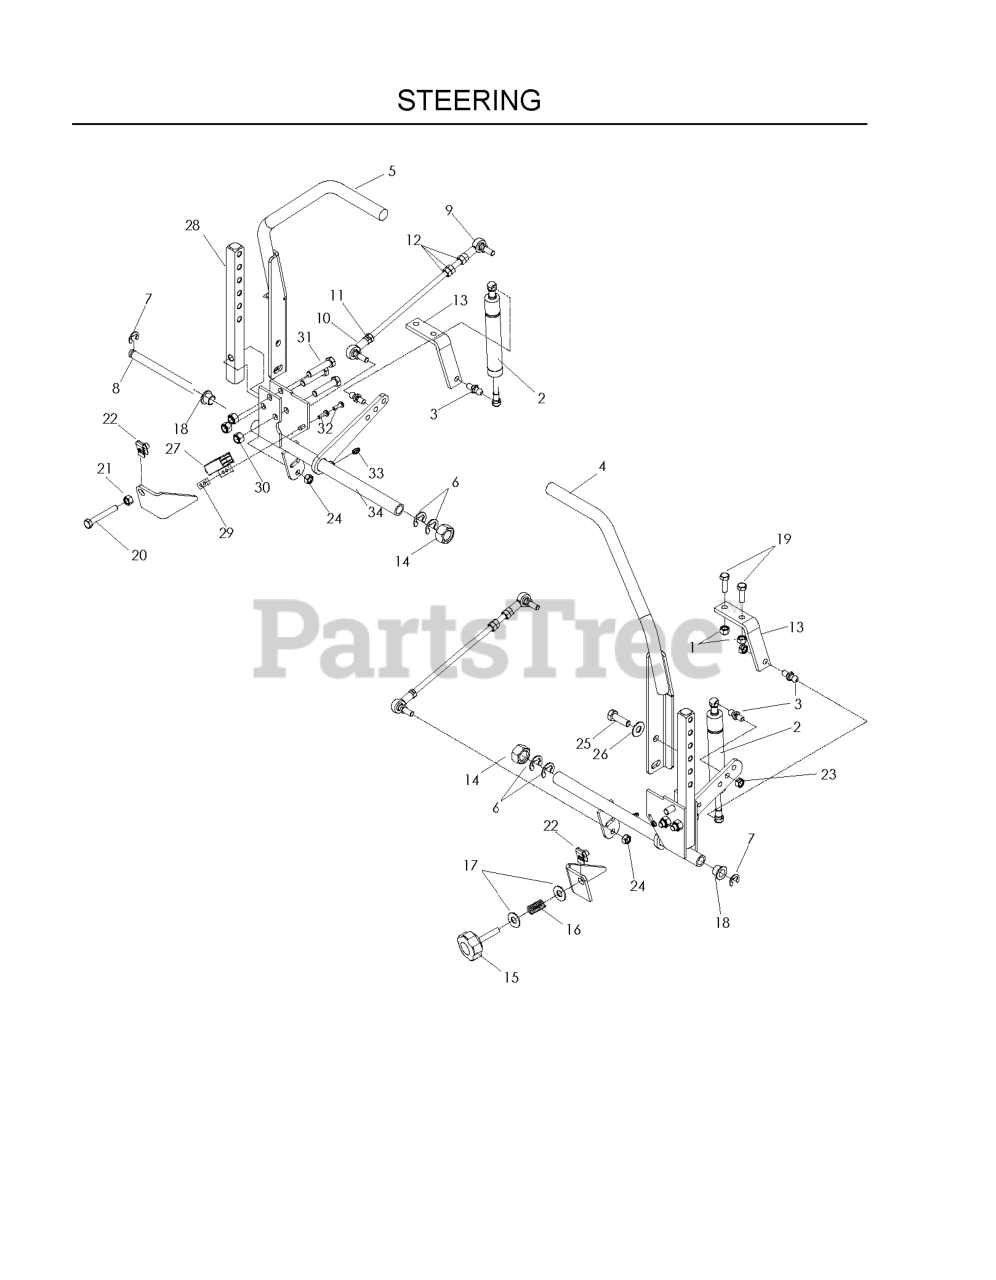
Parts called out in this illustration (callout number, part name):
1	NUT 5/16 NYLOC
2	DAMPENER W/EXT SEAL
3	STUD.BALL.10MM
4	ASSEMBLY, DRIVE LEVER LT
5	ASSEMBLY, DRIVE LEVER RT
6	E-RING 5/8
7	E-RING 1/2 (2 2)
8	CONTROL SHAFT
9	SPHERICAL ROD END, LH
10	SPHERICAL ROD END, RH
11	NUT 5/16F LEFTHAND
13	DAMPENER BRACKET
14	NUT 3/4 X 16 HEX CTR
15	ADJUSTMENT KNOB
16	COMPRESSION SPRING
17	WASHER 5/16 FLAT
19	HCS 5/16C X 1
20	HCS 5/16-18X1-3/4 TPBLT
21	NUT 5/16C HEX
22	U-CLIP 5/16-18 NUT RETAINER
23	NUT 5/16C CENTERLOCK
24	NUT 5/16F NYLOC
25	HCS 3/8-16X1.GRD.5.ZD
26	WASHER, 3/8 DISC SPRING SPEC
27	SWITCH, INTERLOCK
28	CONTROL ARM
29	TAPPED PLATE
30	NUT 3/8-16 NYLOC
31	HCS 3/8-16 X 1 3/4 GR5
32	SCREW #10-24 X 5/8
33	ZERK
34	CONTROL ASM - ADJ, LT
